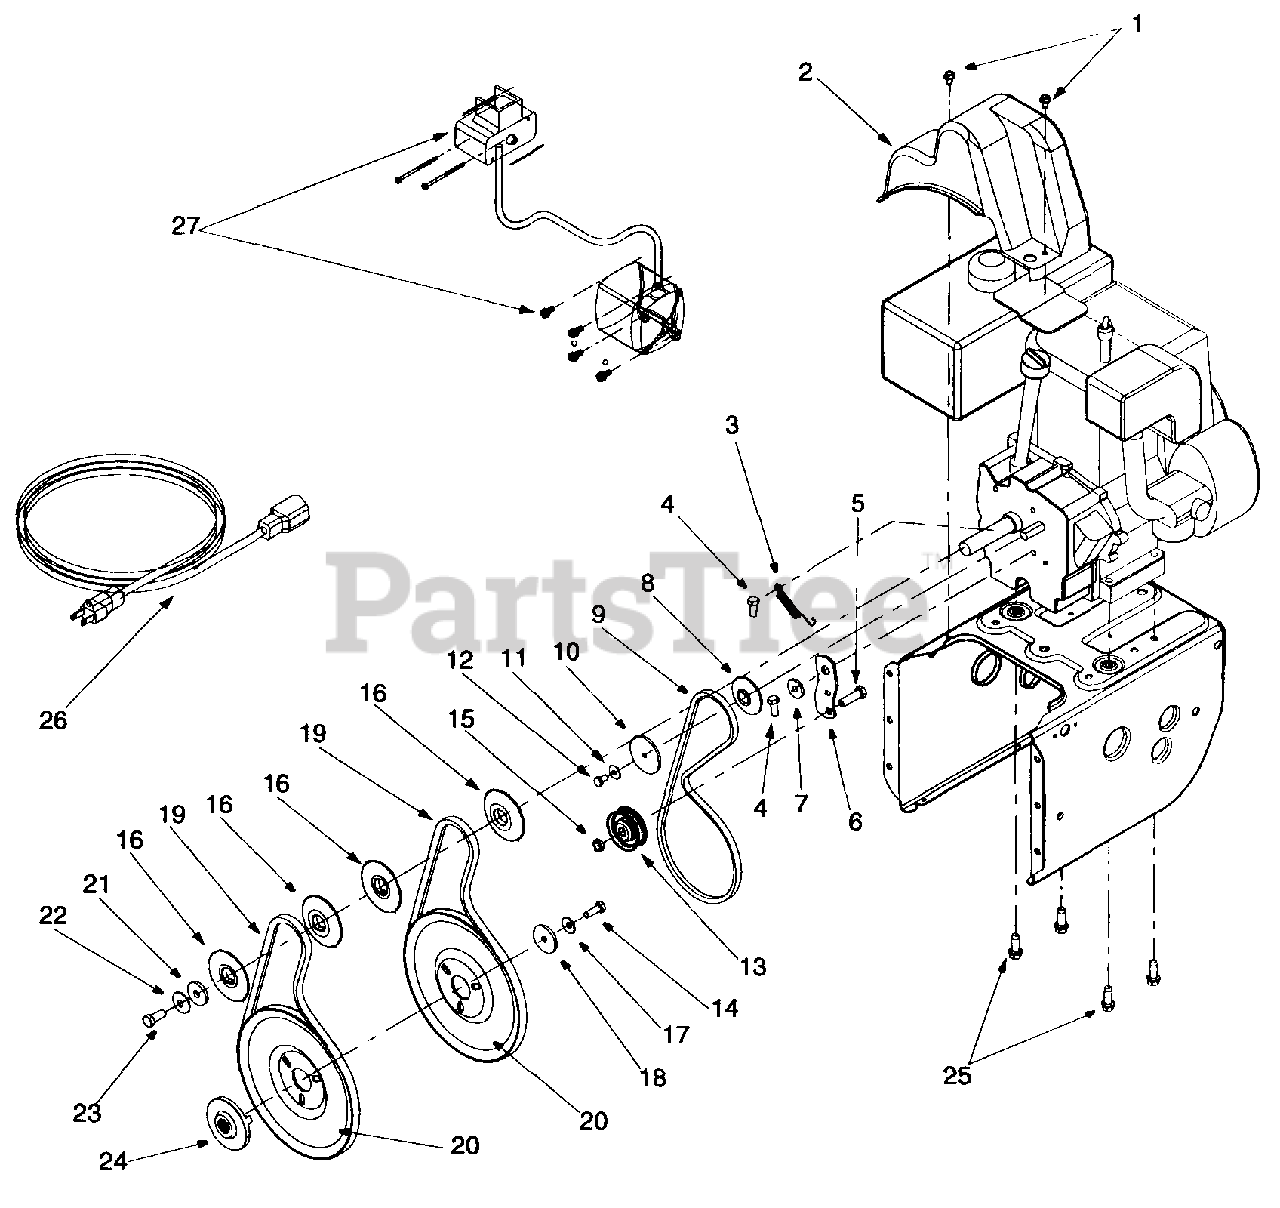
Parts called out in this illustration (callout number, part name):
1	Hex Washer Screw 1/4-20 x .50
2	Belt Cover
3	Extension Spring
4	Hex Screw 5/16-24 x .75
5	Hex Cap Screw 3/8-16 x 1.25
8	Pulley Half
9	V-Belt
10	Pulley Half
11	Bell Washer
12	Hex Cap Screw 1/4-28 x .50
13	Flat Idler
14	Lock Hex Cap Screw 5/16-24
15	Lock Jam Nut 3/8-16
16	Pulley Half
17	Bell Washer
18	Flat Washer
19	Belt
20	Auger Pulley
21	Flat Washer 3/8 x 1.25 OD
22	Bell Washer
23	Hex Cap Screw 3/8-24
24	Adapter Pulley
25	Hex Screw 3/8-16 x 1.0
26	Extension Cord
27	Electric Start
